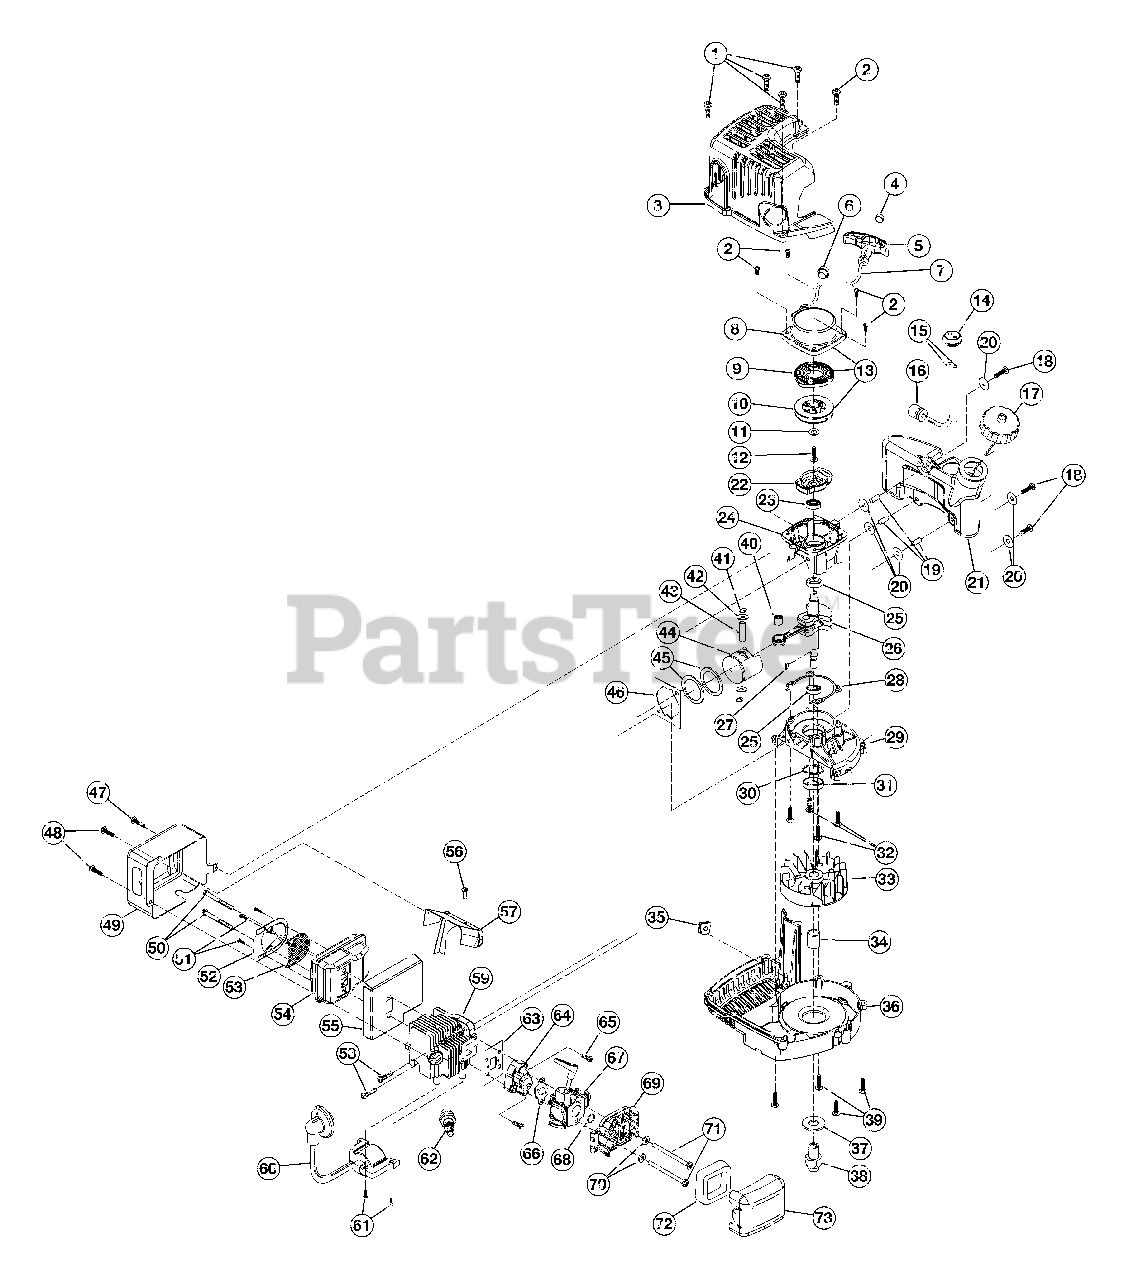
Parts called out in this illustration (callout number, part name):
1	Screw
3	Engine Cover
4	Pull Handle Bushing
5	Pull Handle
6	Rope Guide
8	Recoil Case
9	Recoil Spring
10	Recoil Pulley
11	Washer
12	Screw
13	Recoil Assembly
14	Fuel Line Grommet
15	Fuel Line
16	Fuel Filter
17	Fuel Cap
18	Screw
19	Spacer
20	Washer
21	Fuel Tank Assembly
22	Pawl Assembly
23	Upper Oil Seal
24	Upper Crankcase
25	Bearing
26	Keyed Powershaft Assembly
27	Flywheel Key
28	Crankshaft Gasket
29	Lower Crankcase
30	C-Clip
31	Lower Oil Seal
32	Crankshaft Screw
33	Flywheel
34	Spacer
35	Spark Wire Grommet
36	Lower Engine Cover
37	Washer
38	Impeller Nut
39	Shroud Screws
40	Needle Bearing
41	Retaining Ring
42	Piston Spacer
43	Piston Pin
44	Piston
45	Piston Ring
46	Cylinder Gasket
49	Muffler Cover
50	Muffler Bolt
51	Spark Arrestor Screw
52	Spark Arrestor Hood
53	Spark Arrestor
54	Muffler Assembly
55	Muffler Gasket
57	Cylinder Cover
58	Cylinder Bolt
59	Cylinder
60	Module
61	Module Screw
62	Spark Plug
63	Insulator Gasket
64	Insulator
65	Insulator Screw
66	Carburetor Gasket
67	Carburetor
68	O-Ring
69	Air Cleaner Assembly
70	Washer
71	Air Cleaner Screw
72	Air Filter
73	Air Filter Cover
